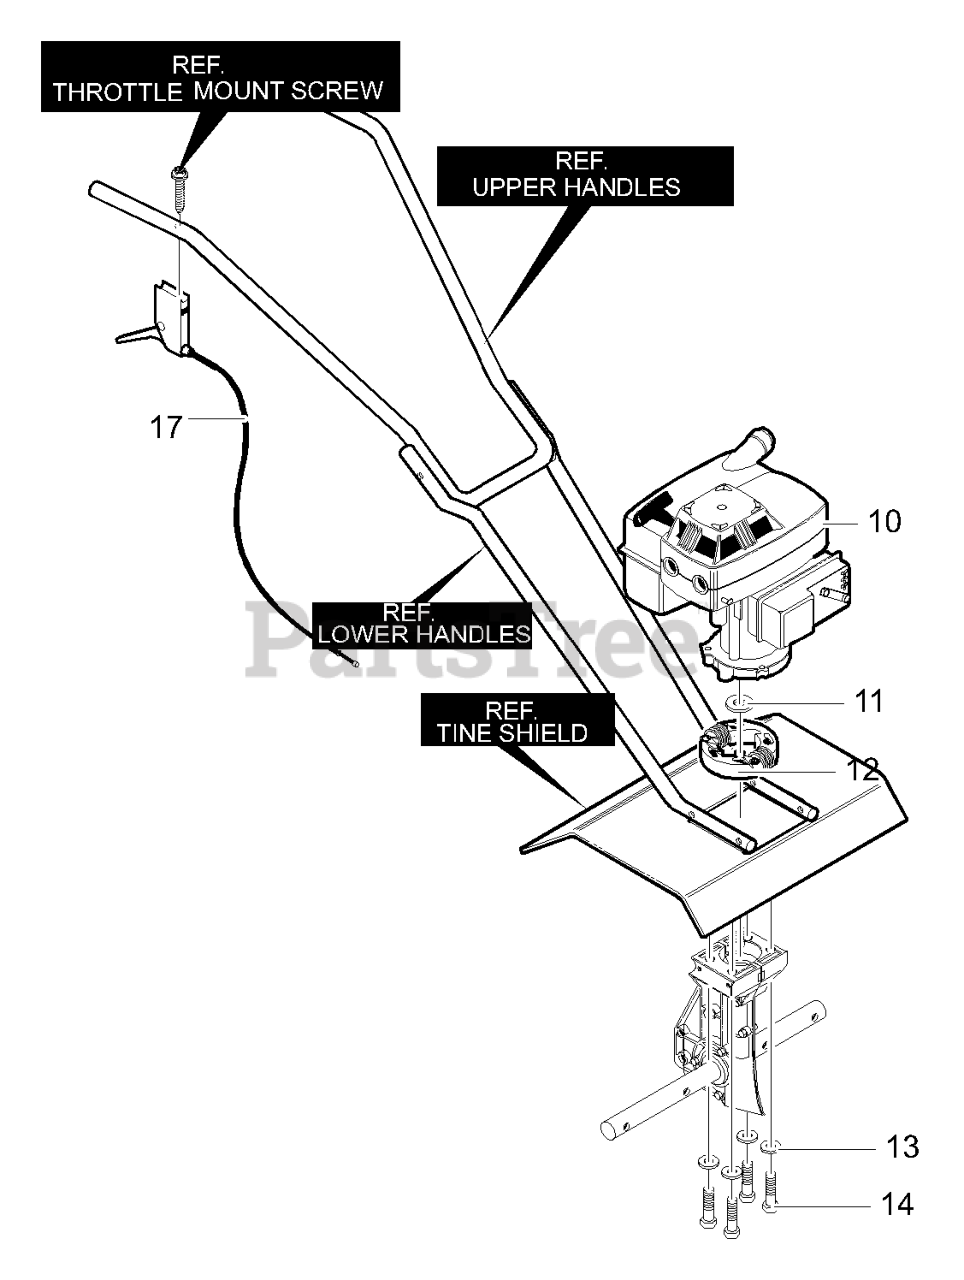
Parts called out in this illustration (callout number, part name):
10	2.0HP Engine
11	Flat washer
13	Washer
14	Screw
17	Cable, Throttle
